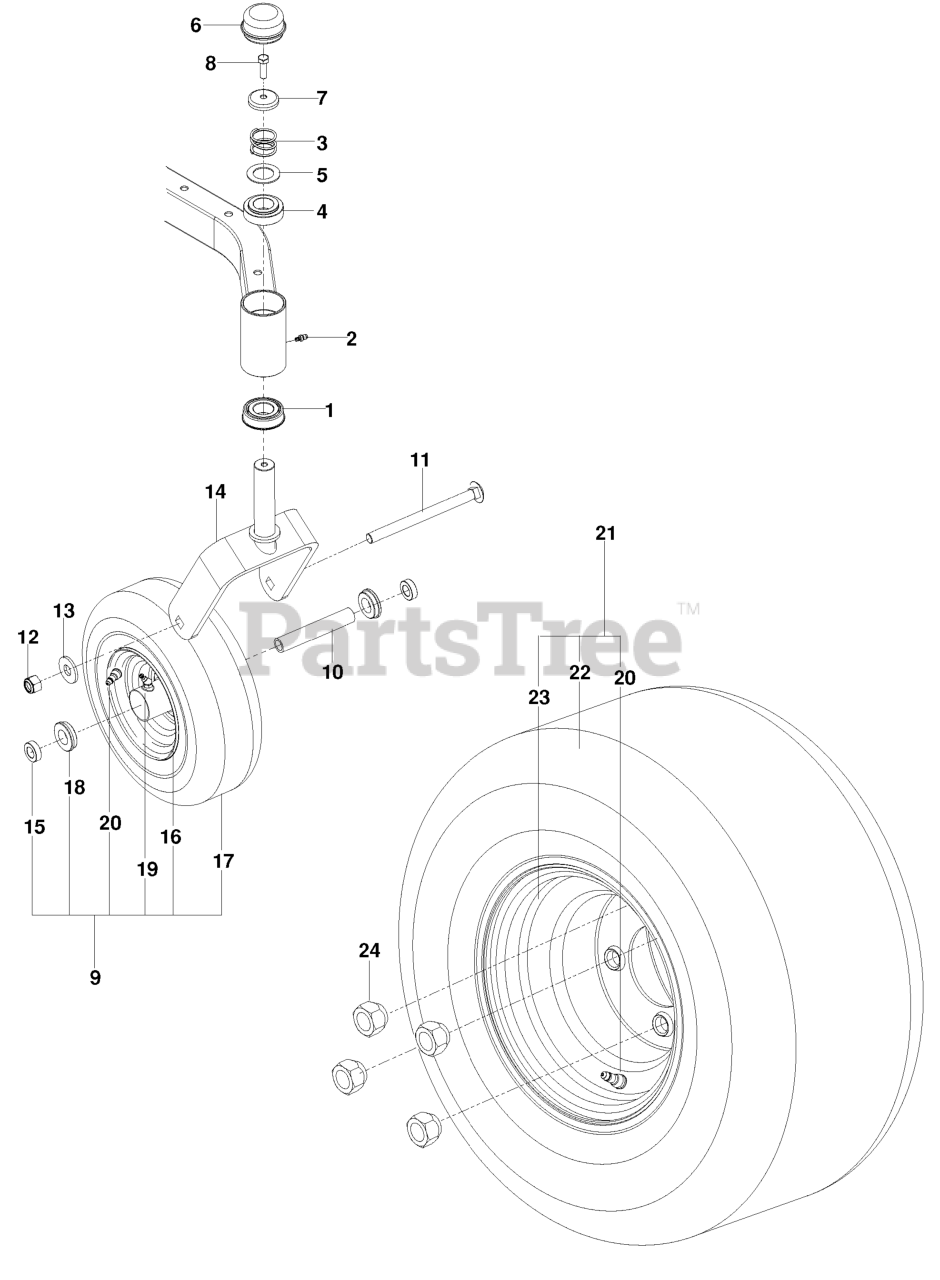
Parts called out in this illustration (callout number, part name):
1	BEARING FLANGED
2	ZERK, 3/16, DRIVE IN
3	SPRING, CASTER
4	BUSHING, CASTER
5	WASHER, 1.025 ID X 1.64
6	GREASE CAP
7	CASTER.PLUG
8	HCS 5/16C X 1
9	TIRE COMPLETE
11	RHSNB 1/2-13 X 6.50 GR2 ZD
12	NUT 1/2-13 HEX CNTRLK GR 5 ZD
13	WASH USS FLAT 1/2
14	YOKE.CASTER.ORANGE
15	SPACER, 5/16"
17	TIRE - CASTER
18	BEARING RETAINER
19	ZERK
20	VALVE STEM TR-412
21	TIRE ASM, 20 X 8-8
22	TIRE 20 X 8, TURF
23	RIM.8X7.W/8".OFFSET.SILVER.ZTR
24	LUG NUT 1/2F
